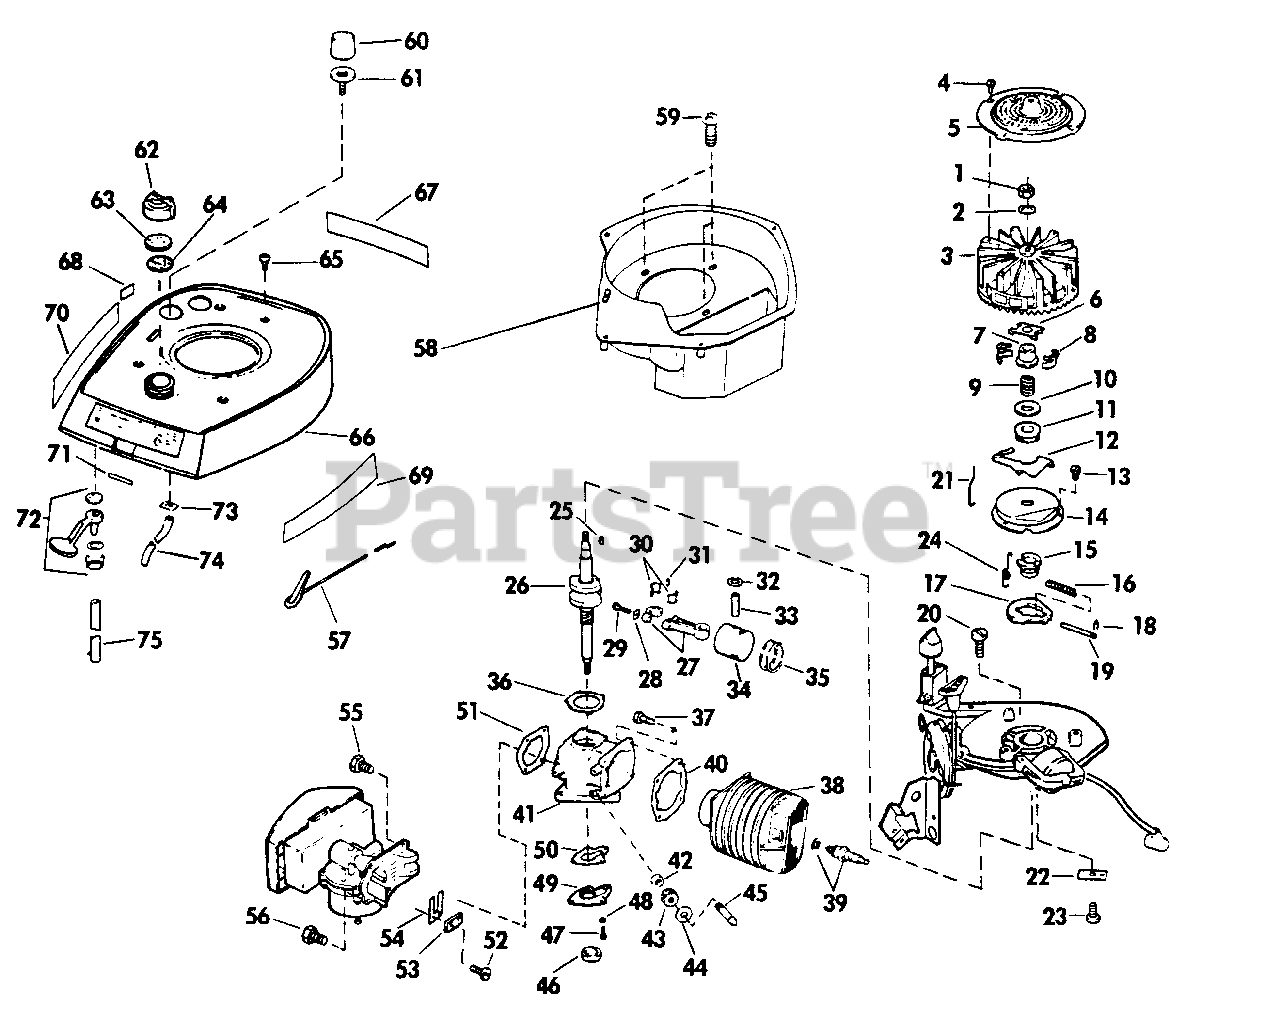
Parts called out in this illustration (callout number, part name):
1	Nut-Flywheel
2	Lockwasher-Flywheel
3	Flywheel & Screen Assy.
4	Screw-Thd. Cutting
5	Screen & Cup
6	Yoke-Governor
7	Collar-Governor
8	Weight-Governor
9	Spring-Governor
10	Thrust Washer
11	Collar-Thrust
12	Lever-Governor
13	Screw-Attaching Dust Cover
14	Dust Cover
15	Cam-Spark Advance
16	Spring-Spark Advance
17	Flyweight-Spark Adv.
18	Retainer-Spring
19	Pin-Spark Advance
20	Screw-Arm. Plate to Crankcase
21	Rod Governor
22	Tab
23	Screw
24	Spring-Variable Speed
25	Key-Crankshaft
26	Crankshaft
27	Connecting Rod Assy.
28	Lockplate
29	Screw-Connecting Rod
30	Liners-Connecting Rod (Set)
31	Needle Bearing Set
32	Retaining Ring
33	Wrist Pin
34	Piston
35	Ring Set
36	Gasket-Crankcase to Arm. Plate .005 in.
36	Gasket-Crankcase to Arm. Plate .010 in.
37	Screw-Cylinder to Crankcase
38	Cylinder & Sleeve Assy.
39	Spark Plug & Gasket
40	Gasket-Cylinder to Crankcase
41	Crankcase, Bearing & Seal
42	Seal, Driveshaft
43	Gear
44	Washer-Thrust
45	Driveshaft
46	Seal, Crankshaft
47	Screw
48	Washer
49	Cover
50	Gasket
51	Gasket-Reed Plate
52	Screw-Machine
53	Plate-Back-up
54	Reed
55	Screw
56	Screw
57	Knob & Rod
58	Air Baffle Assy.
59	Screw-Baffle
60	Bulb-Primer
61	Base-Primer
62	Cap, Gas Tank
63	Gasket
64	Baffle
65	Screw, Cover
66	Cover, Engine
67	Decal, Lawn-Boy
68	Decal, Caution
69	Decal, R.H.-21"
70	Decal, L.H.-21"
71	Spring, Bar
72	Fuel, Shut Off
73	Fastener, Primer
74	Tube Primer
75	Fuel Hose
